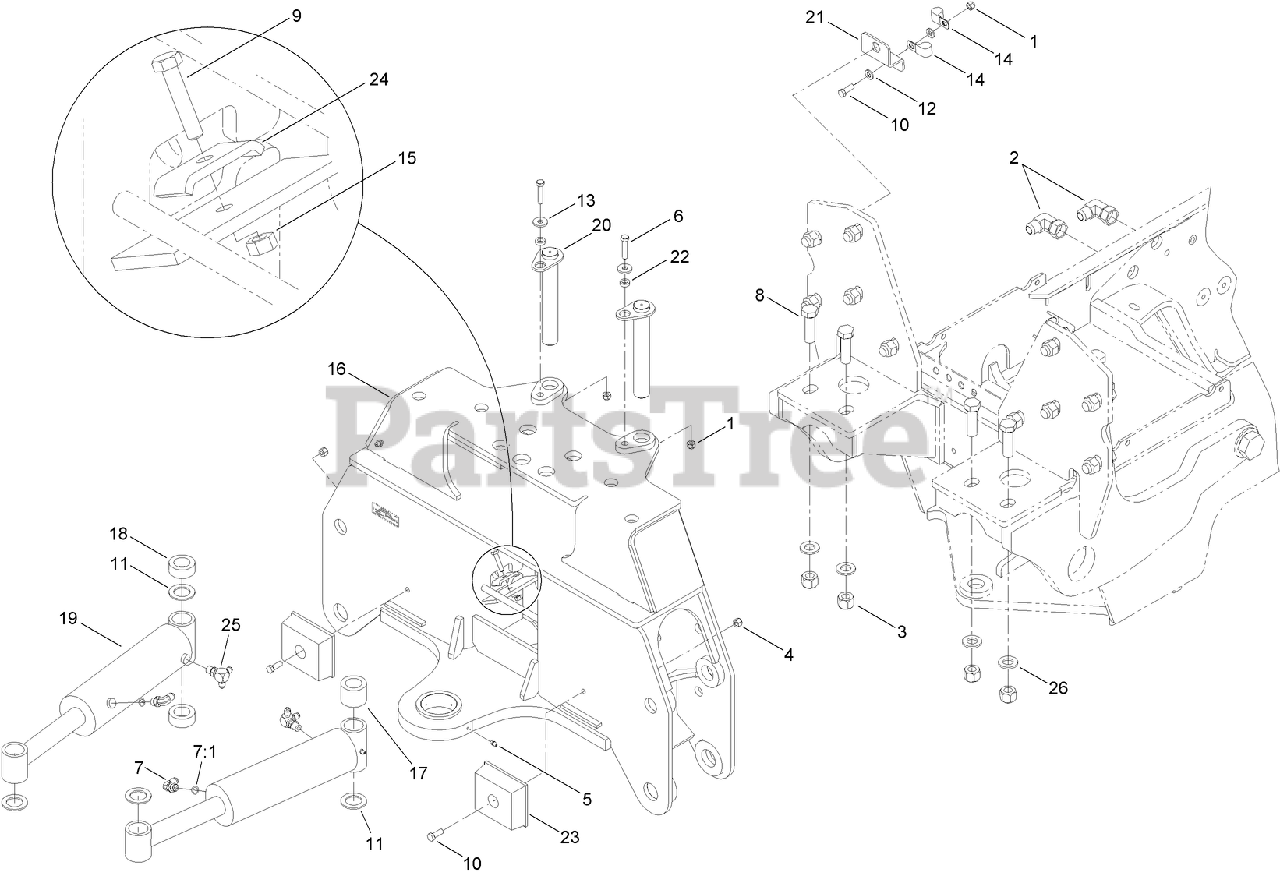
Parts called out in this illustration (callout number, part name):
1	NUT-HEX
2	FITTING-ELBOW, 90
3	NUT-HEX LOCK
4	NUT
5	FITTING-GREASE
6	SCREW-HH
7	FITTING-ELBOW, 90 DEG
7:1	O-RING
9	SCREW-HH
10	SCREW-HH
12	WASHER-FLAT
14	CLAMP-R
15	NUT-LOCK, CONE
16	FRAME-BACKHOE
17	BOSS-PIN (40MM)
18	BOSS-PIN (20.5MM)
19	HYD CYLINDER ASM
20	PIN-PIVOT W/ FLAG
21	BRACKET-MOUNTING, TUBE
23	BUMPER
24	CLAMP-TUBE
25	FITTING
26	WASHER-Flat
